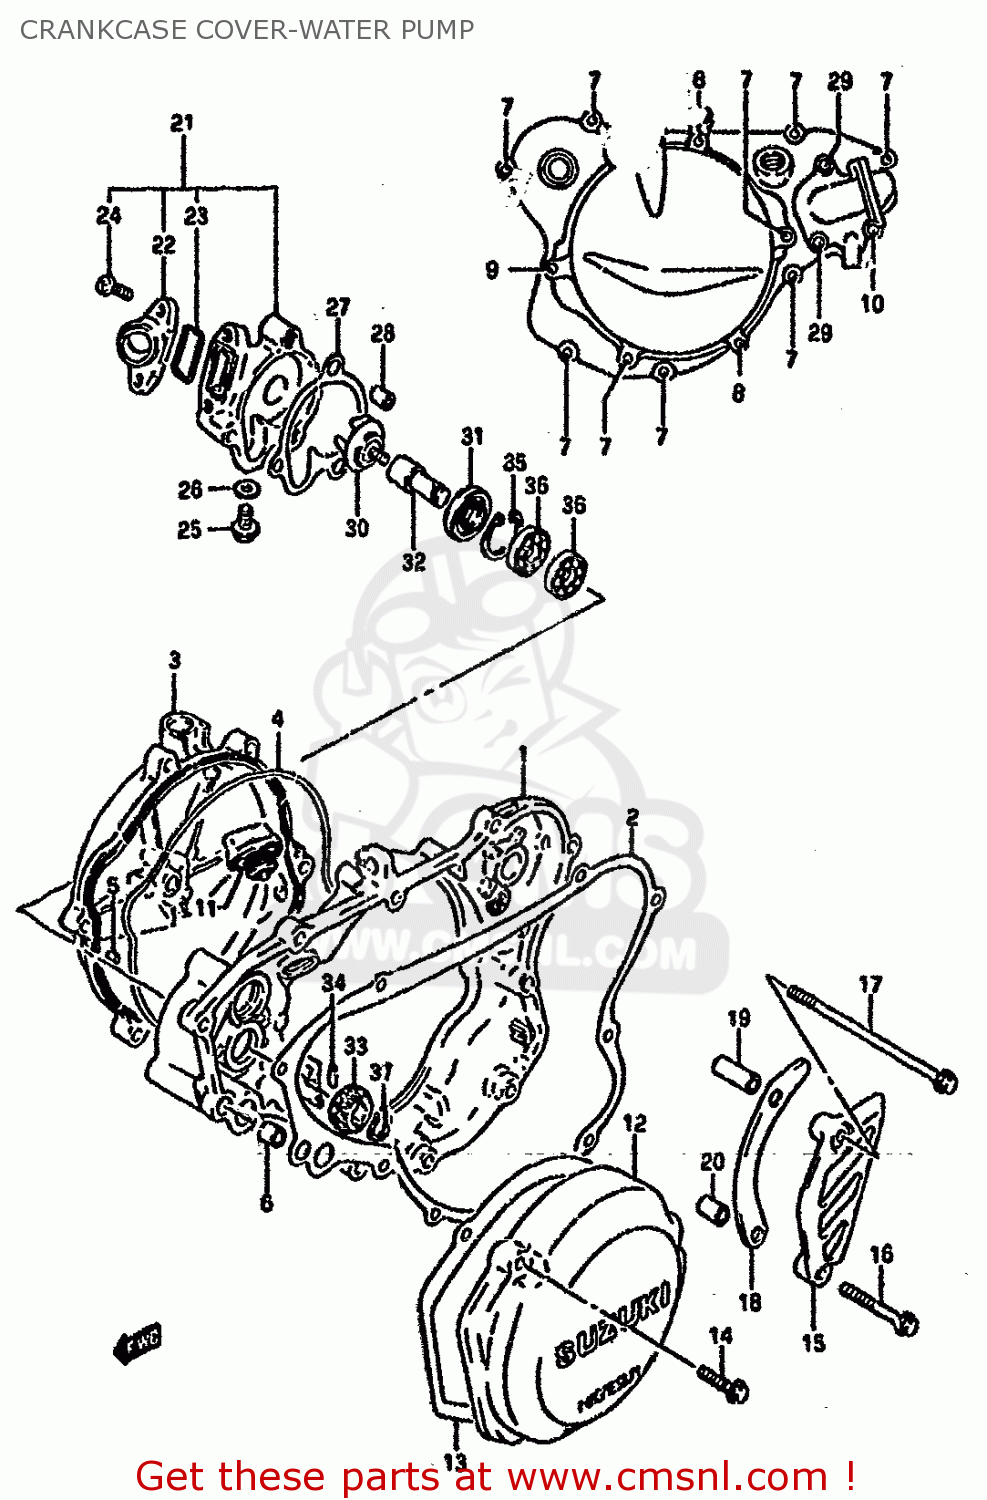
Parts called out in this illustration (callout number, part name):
1	COVER,CLUTCH
2	GASKET,CLUTCH COVER (NAS)
3	COVER,CLUTCH,OUTER
4	O RING,CLUTCH COVER OUTER
5	PIN
6	PIN
7	BOLT
8	BOLT
9	BOLT
10	BOLT(6X100)
11	PLUG SET
12	COVER
13	GASKET,MAGNETO COVER (NAS)
14	BOLT
15	COVER,SPROCKET
16	BOLT
17	BOLT(6X100)
18	PLATE,FR CHAIN GUIDE
19	SPACER(6.5X10.5X25)
20	SPACER(6.5X10.5X12)
21	CASE,WATER PUMP
22	CONNECTOR
23	O RING,WATER PUMP CONNECTOR
24	SCREW
25	BOLT
26	WASHER
27	GASKET,WATER PUMP CASE (NAS)
28	PIN
29	BOLT
30	IMPELLER,WATER PUMP
31	SEAL,WATER PUMP OIL
32	SHAFT,WATER PUMP
33	GEAR,WATER PUMP DRIVEN
34	PIN(3X13.8)
35	CIRCLIP
36	BEARING
37	CIRCLIP,10MM
